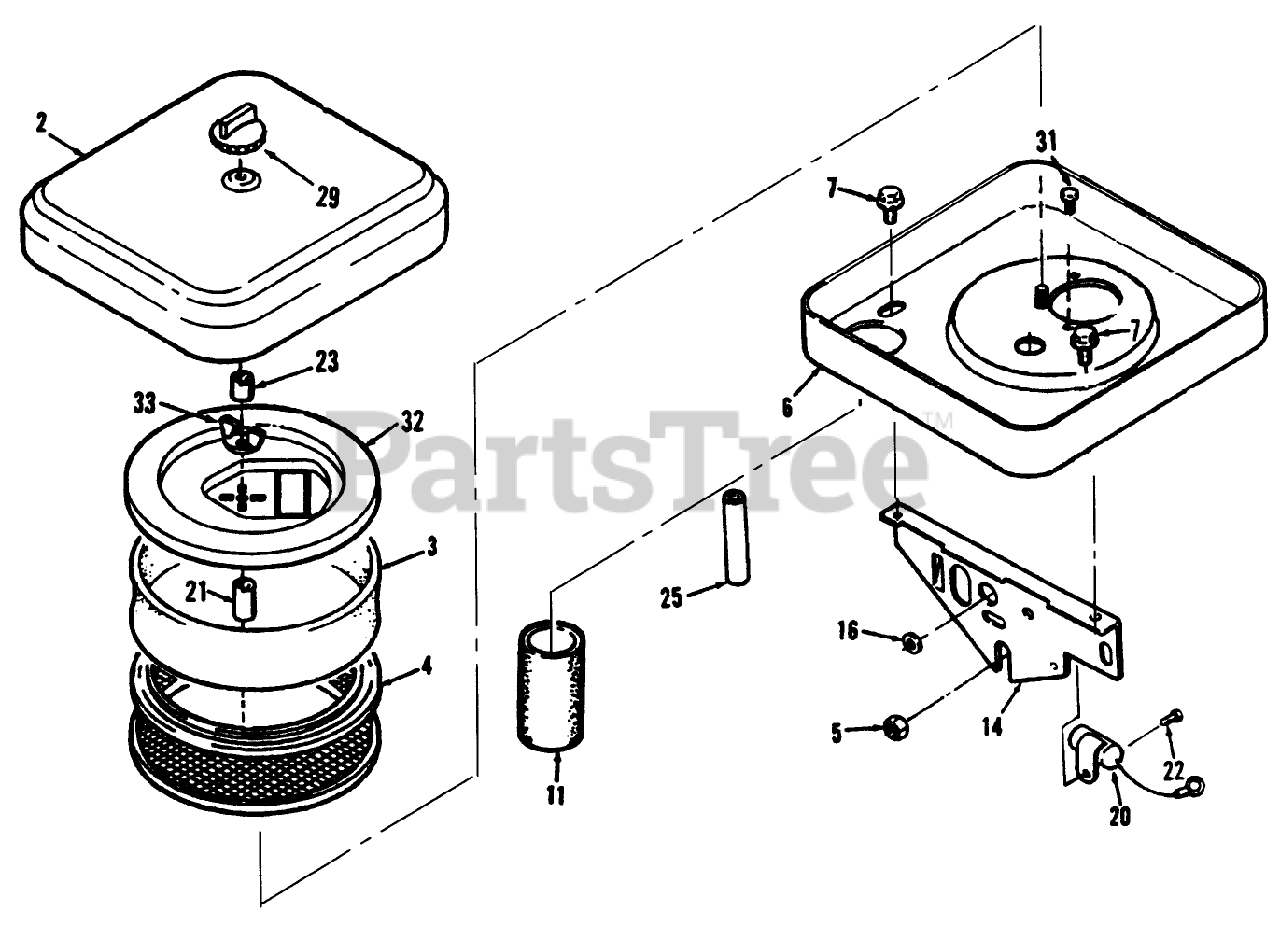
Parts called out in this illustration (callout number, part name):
2	COVER - AIR CLEANER
3	AIR CLEANER ELEMENT
7	SCREW-TAPPING
14	SUPPORT-AIR CLEANER
16	GROMMET
20	CONDENSER
32	ELEMENT COVER KIT
